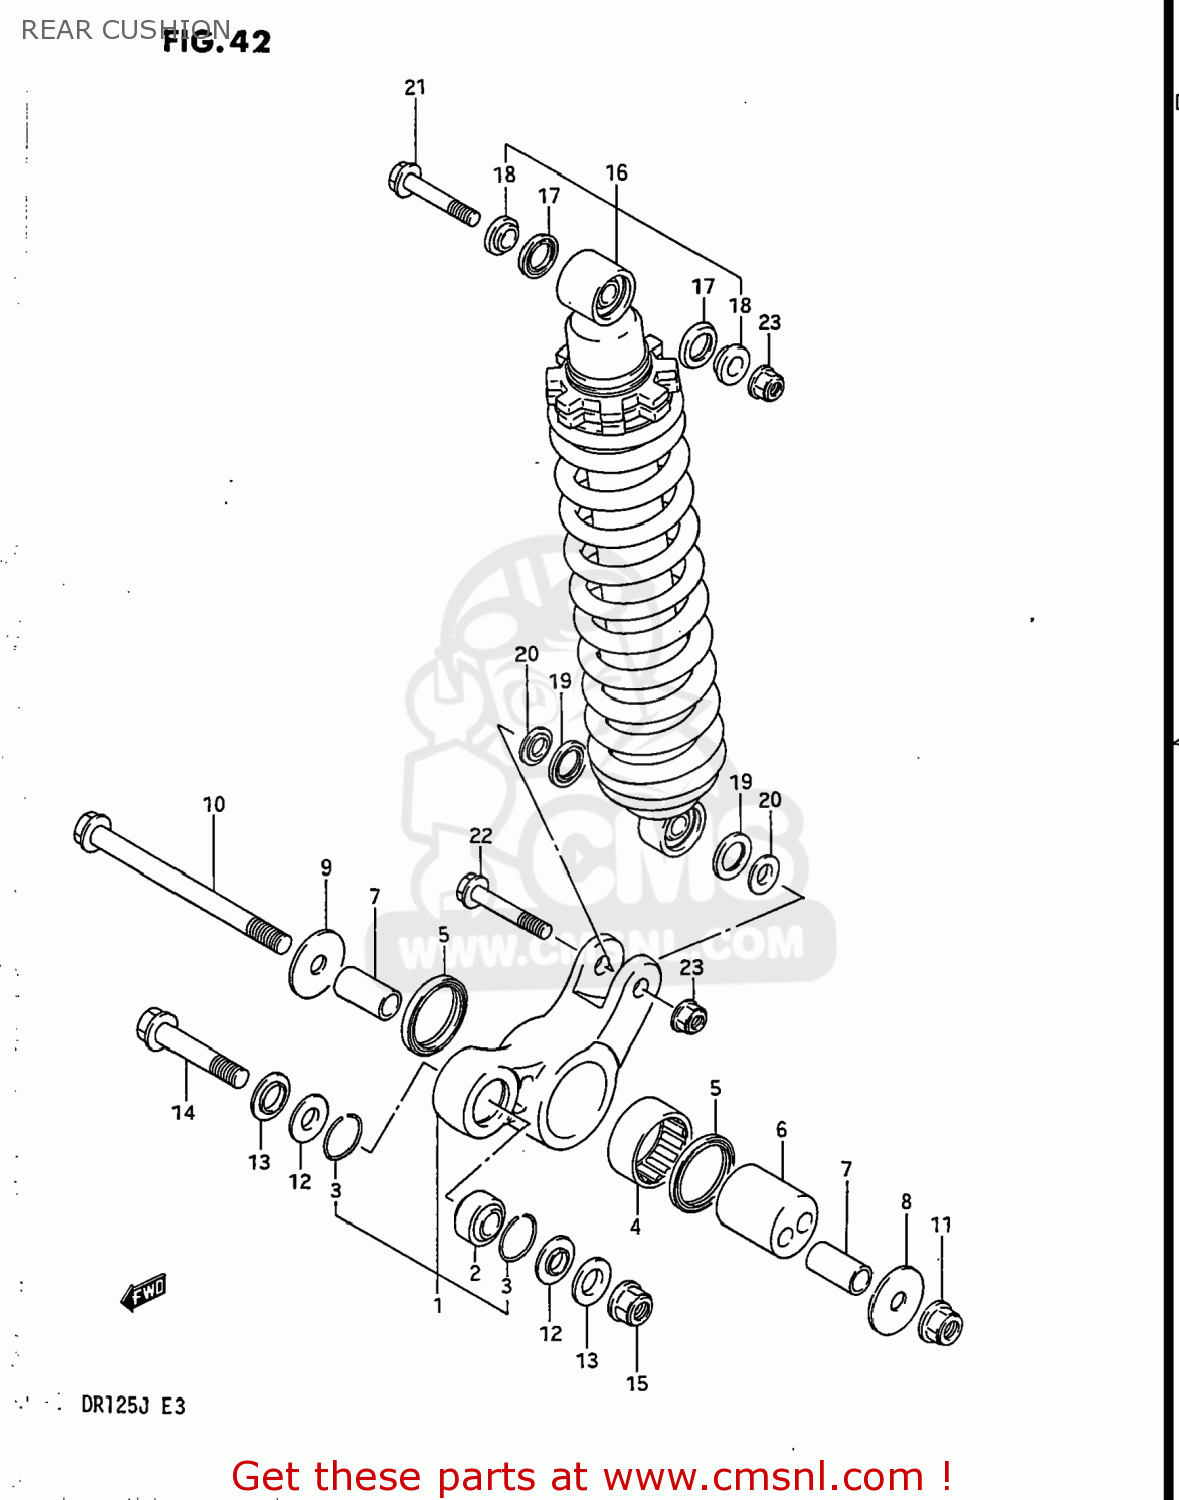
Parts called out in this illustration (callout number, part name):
1	LEVER SET,RR CUSHION
2	BEARING(12X26X16)
3	RING,STOPPER
4	BEARING(37X47X20)
5	SEAL,DUST
6	SPACER,RR SUSPENSION ECCENTRIC
7	SPACER,CUSHION LEVER SHAFT
8	WASHER(12X40X3)
9	WASHER,THRUST,R
10	SHAFT,REAR CUSHION LEVER
11	NUT 12MM
12	SEAL,RR CUSHION ROD DUST
13	SPACER,RR CUSHION ROD
14	BOLT,CUSHION LEVER FR
15	NUT 12MM
16	ABSORBER ASSEMBLY,REAR SHOCK
17	DUST SEAL
18	SPACER
19	SEAL,DUST
20	COLLAR
21	BOLT,REAR SHOCK ABSORBER
22	BOLT(10X48)
23	NUT
